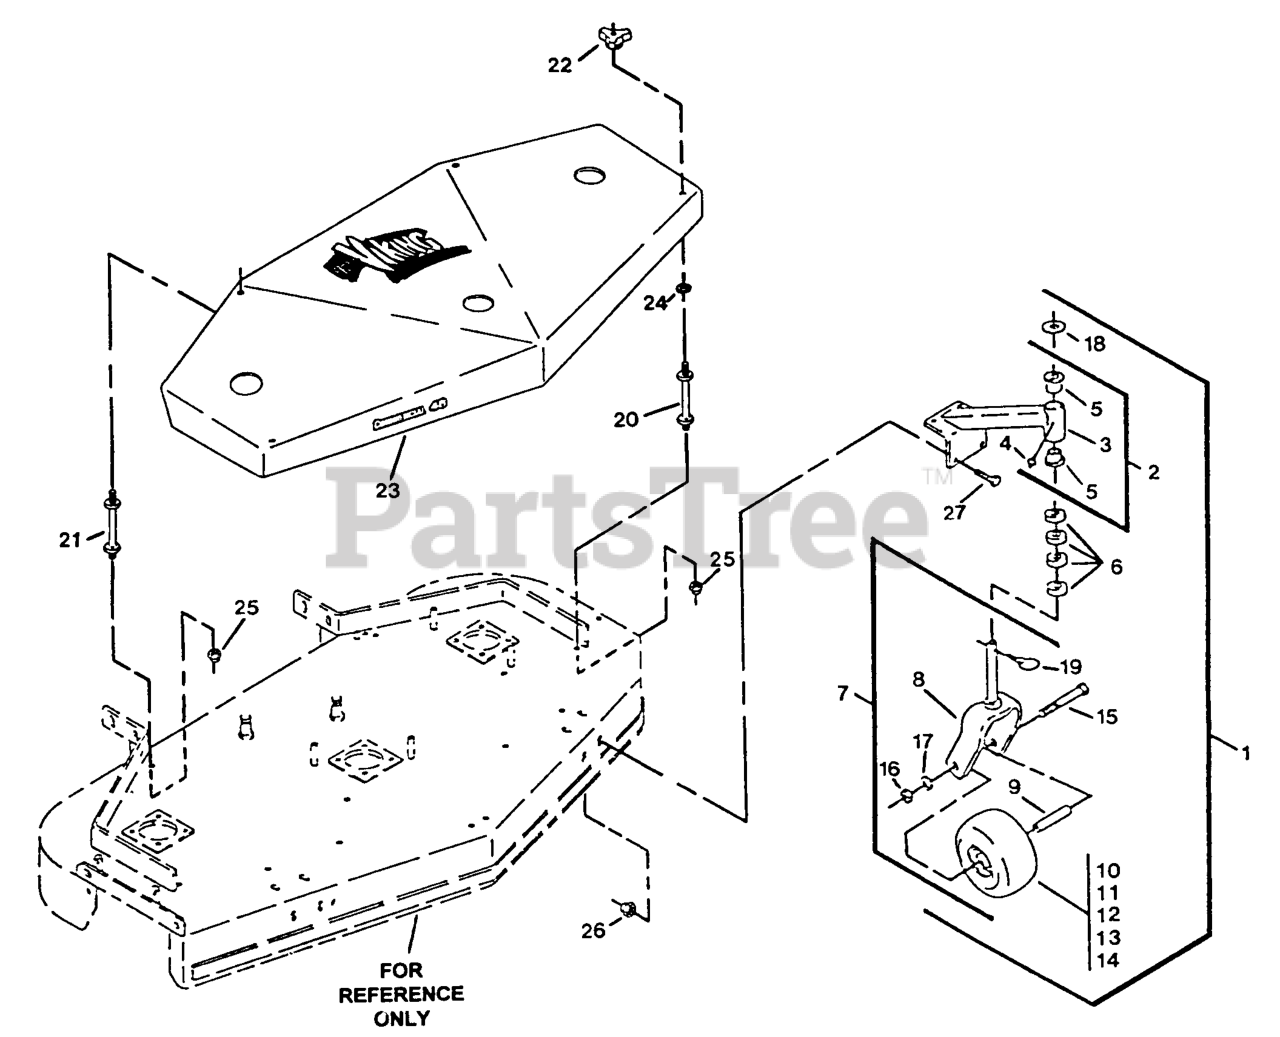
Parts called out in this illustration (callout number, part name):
1	CASTER/MOUNT ASM
2	SUPPORT ASM
5	BEARING-FLANGED
6	SPACER-CASTER
13	BEARING
14	BUSHING
18	WASHER-FLAT
20	STUD-SHIELD, BELT (SHORT)
21	STUD-SHIELD, BELT (LONG)
22	KNOB-3 PRONG
